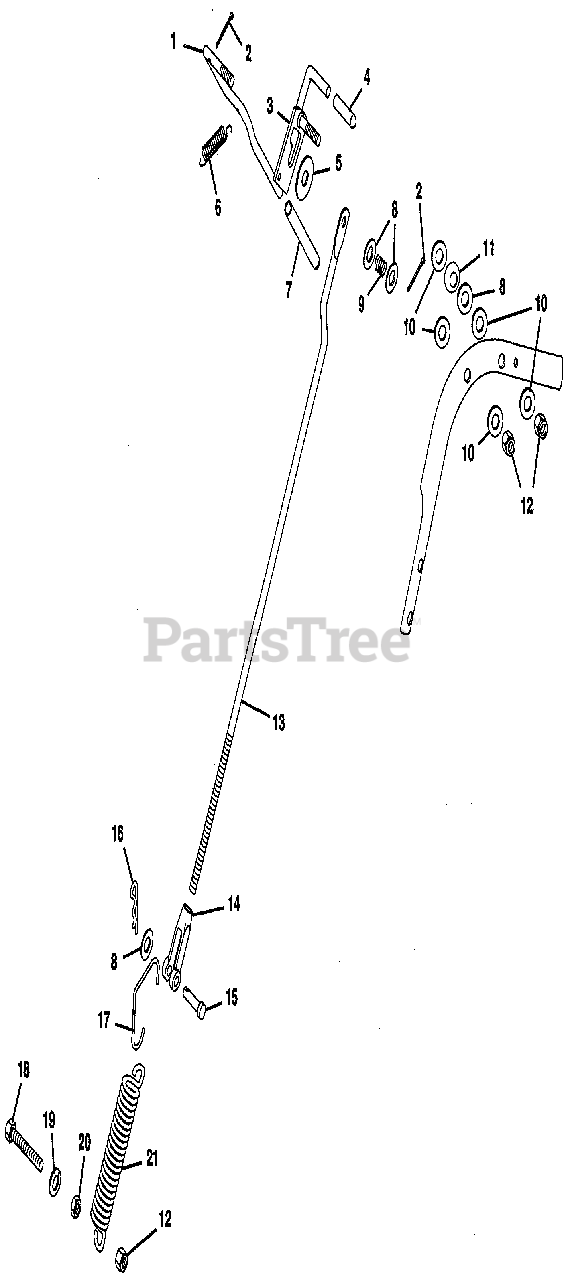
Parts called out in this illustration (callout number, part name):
1	LVR, HAND CONTROL
2	PIN-COTR .09 X .75 PL
3	WLDMT NEUTRAL LOCKING LEVER
4	TIP, BRAKE LOCK LEVER
5	WASHER, FLAT .438 X 1.375 X .083
6	SPRING, EXTENSION
7	GRIP, HAND CLUTCH LEVER
8	WASHER, FLAT .406 X .812 X .065
9	SPRING, COMPRESSION
10	WASHER, NYLON .375 X .75 X .06
11	WASHER, SPRING .375 I.D.
12	NUT, LOCK 3/8-16
13	ROD, STEERING CONTROL
14	CLEVIS, 3/8-24 ADJUSTABLE
15	PIN, CLEVIS
16	PIN, COTTER HAIR
17	HOOK, SPRING
18	BOLT, HEX 3/8-16 X 2.50
19	WASHER, LOCK 3/8 REG.
20	NUT, HEX 3/8-16
21	SPRING, EXT. LE-105J6
